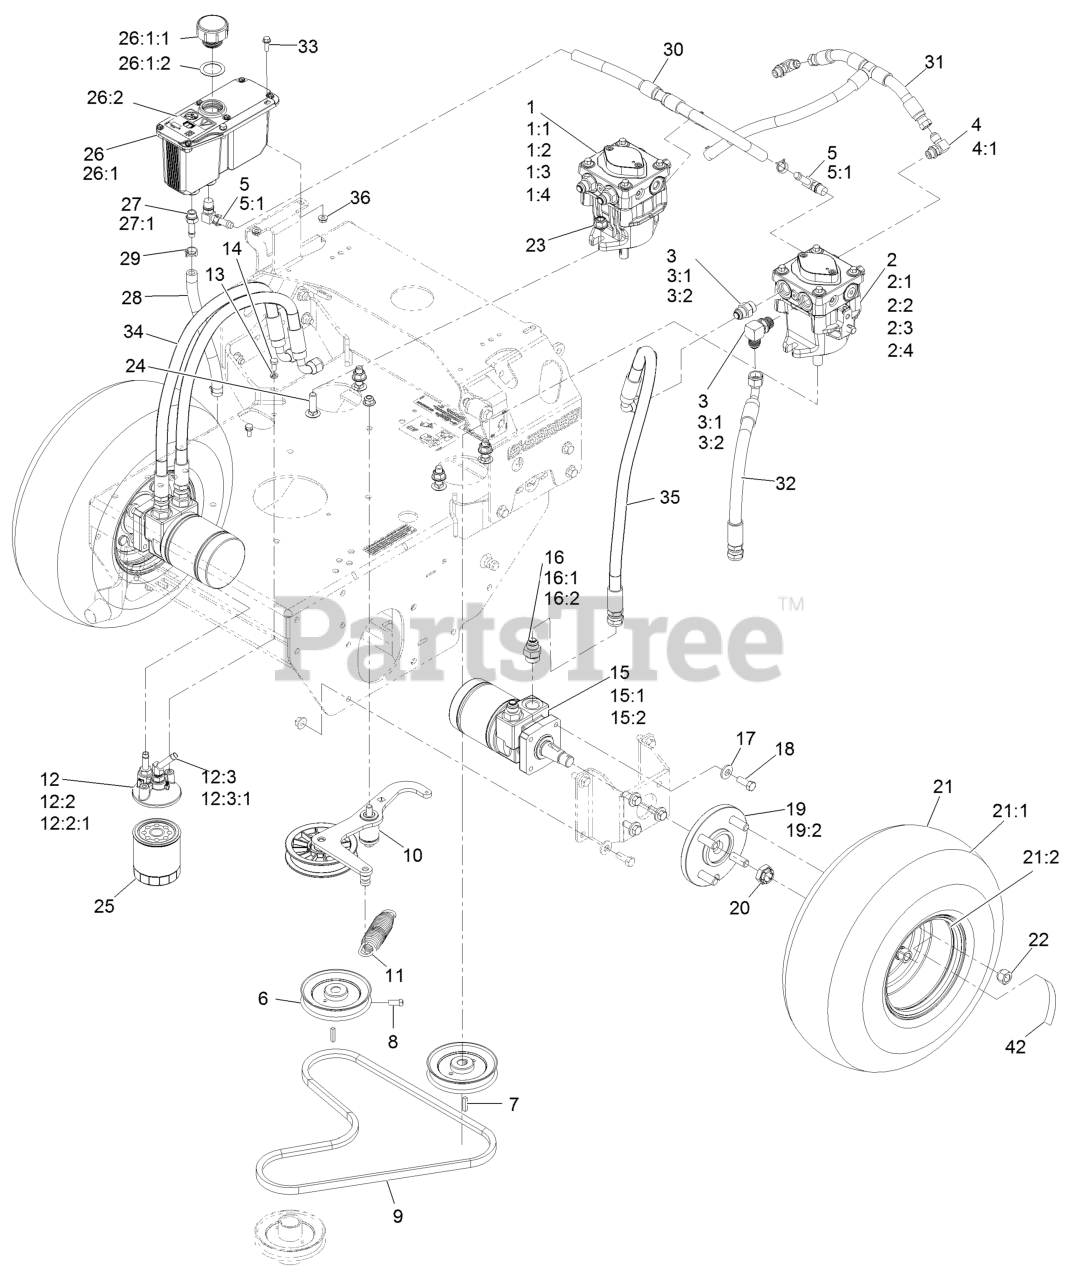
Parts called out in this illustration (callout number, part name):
1	RH HYD PUMP ASM
1:1	INPUT SHAFT KIT
1:2	BEARING-THRUST
1:3	CYLINDER BLOCK KIT
1:4	SEAL OVERHAUL KIT
2	LH HYD PUMP ASM
2:1	INPUT SHAFT KIT
2:2	BEARING-THRUST
2:3	CYLINDER BLOCK KIT
2:4	SEAL OVERHAUL KIT
3	FITTING-STRAIGHT
3	FITTING-90 DEG
4	FITTING-ELBOW, 90 DEG
5	FITTING-ELBOW, 90
5:1	O-RING
6	SHEAVE ASM
8	SCREW-SET, SQH
9	BELT
10	ASM, PUMP IDLER
11	SPRING-EXTENSION
12	ASM, FILTER HEAD
12:2	ADAPTER-STRAIGHT
12:2:1	O-RING
12:3	FITTING-BARBED, 45 DEG
12:3:1	O-RING
13	WASHER-LOCK
14	SCREW-HH
15	HYD MOTOR ASM
15:1	SEAL KIT
15:2	BEARING AND SEAL KIT
16	FITTING-STRAIGHT
16:1	O-RING
17	WASHER-BELLEVILLE
18	SCREW-HH
19	WHEEL HUB ASM
19:2	STUD-WHEEL
20	NUT-LOCK
21	WHEEL AND TIRE ASM
21:1	TIRE-TURFMASTER
21:2	RIM-WHEEL
22	NUT-LUG
23	NUT-HF, NI
24	SCREW-HH
25	FILTER-25 MICRON, BI-DIRE
26:1	Reservoir-HYD
26:1:1	Cap-Reservoir, HYD
26:1:2	GASKET-CAP
26:2	DECAL-WARNING
27	ADAPTER-STRAIGHT
27:1	O-RING
28	HOSE-CHARGE
29	CLAMP-HOSE
30	HOSE-CASE DRAIN
31	HOSE-CHARGE
32	ASM, HP HOSE
33	SCREW-HWH
34	HYD HOSE ASM
35	HYD HOSE ASM
42	DECAL-TORQUE WHEEL LUG-HU
